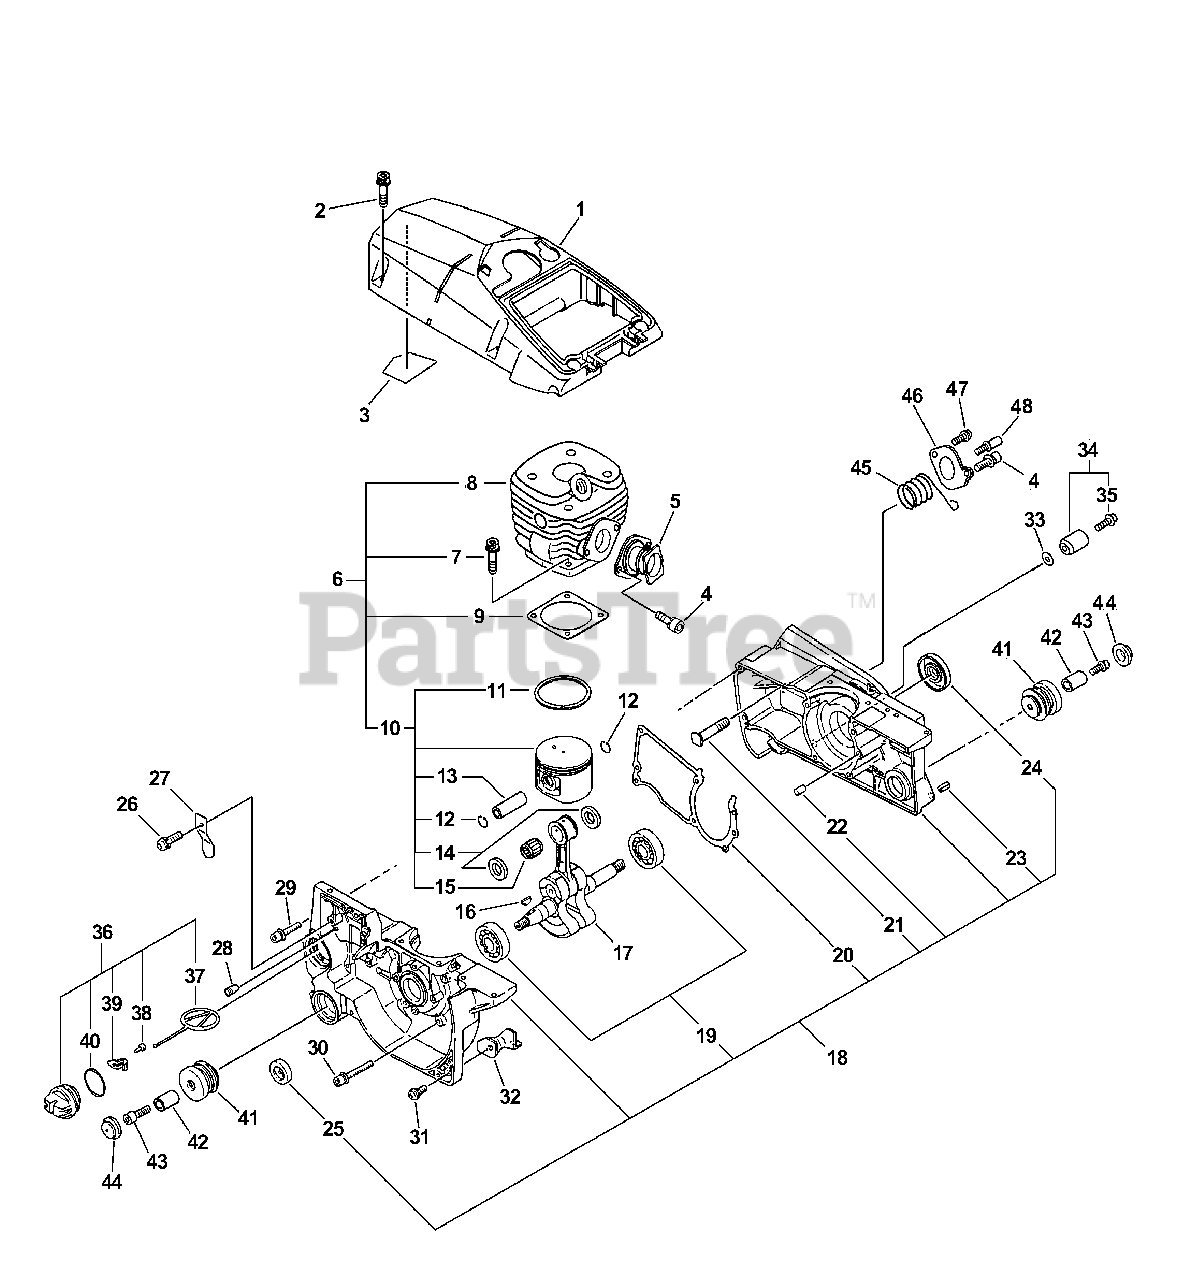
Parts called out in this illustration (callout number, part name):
1	COVER, ENGINE
2	SCREW - 5X20
3	DEFLECTOR, HEAT
4	SCREW - 5X14
5	BELLOWS, INTAKE
6	CYLINDER/PISTON KIT
7	SCREW - 5X25
8	CYLINDER
9	GASKET, CYLINDER
10	PISTON KIT
11	RING, PISTON
12	RING, RETAINING
13	PIN, PISTON
14	SPACER, PISTON
15	BEARING, NEEDLE
17	CRANKSHAFT ASSY
18	CRANKCASE KIT
19	BEARING, BALL - 6202
20	GASKET, CRANKCASE
21	STUD, GUIDE BAR
22	PIN - LOCATING
23	PIN - SPRING -- 5X25
24	SEAL, OIL
25	SEAL, OIL
26	SCREW - 4X8
28	VENT, TANK
29	SCREW - 5X20
30	SCREW - 5X35
31	SCREW - 5X14
32	CUSHION
33	WASHER - 5
34	CHAIN CATCHER KIT
35	SCREW - 5X18
36	CAP ASSY
37	CONNECTOR, CAP
38	SCREW - 3X8
39	RETAINER
40	O-RING - 25
41	CUSHION
42	COLLAR - 5
43	SCREW - 5X25
44	CAP, CUSHION
47	SCREW - 4X8
48	STUD, THREADED
